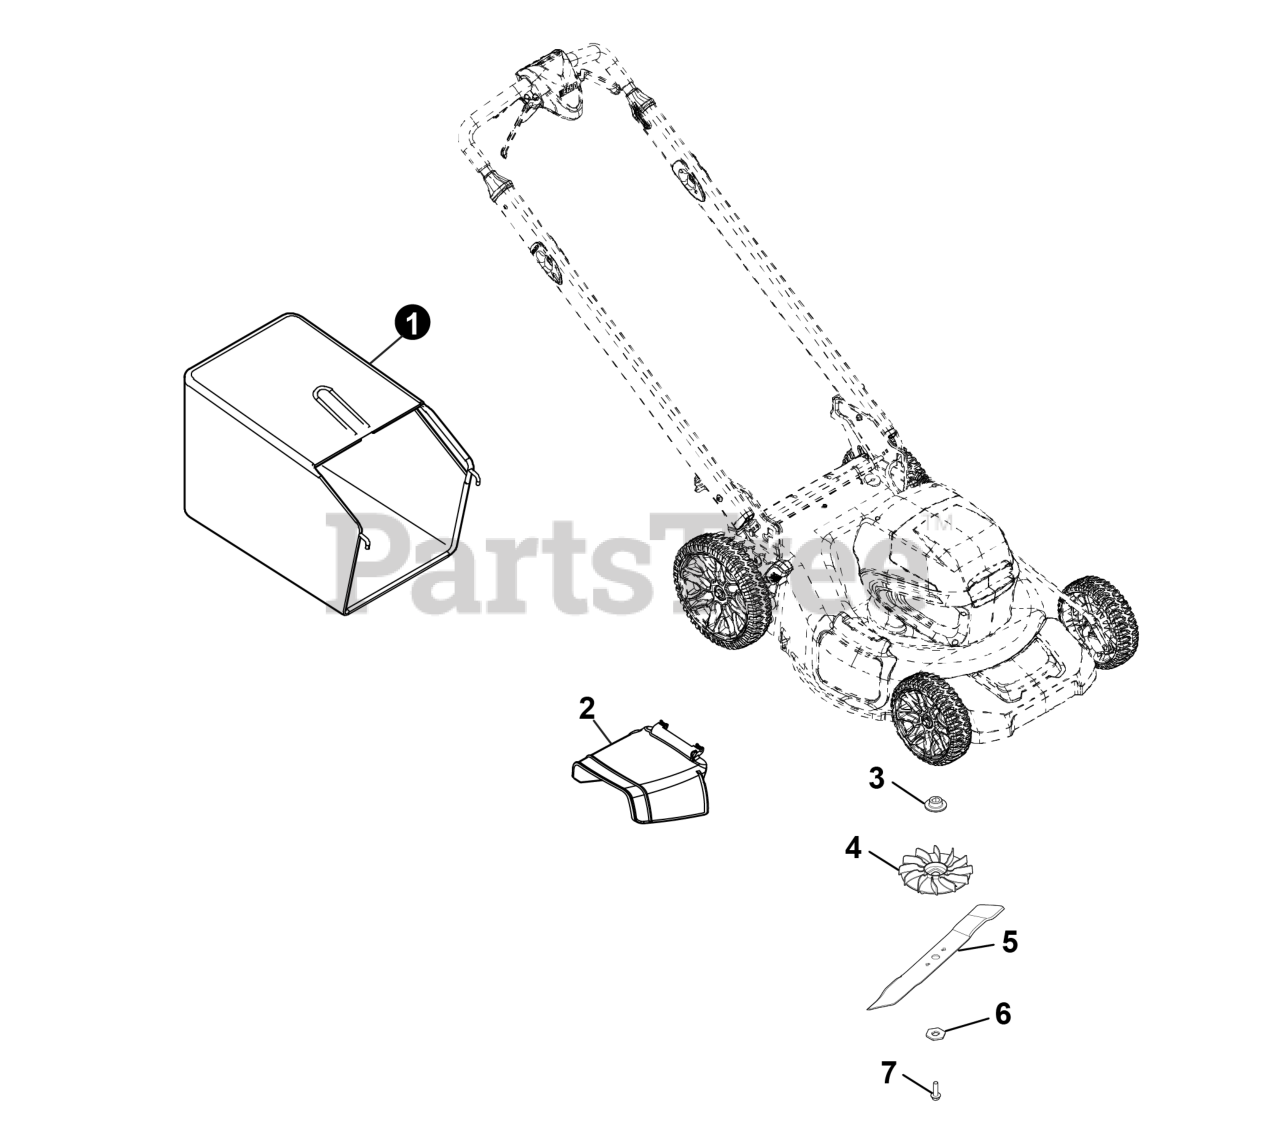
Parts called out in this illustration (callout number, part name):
1	BAG ASSY, GRASS
2	CHUTE, SIDE DISCHARGE
3	ADAPTER,BLADE
7	BOLT, BLADE
